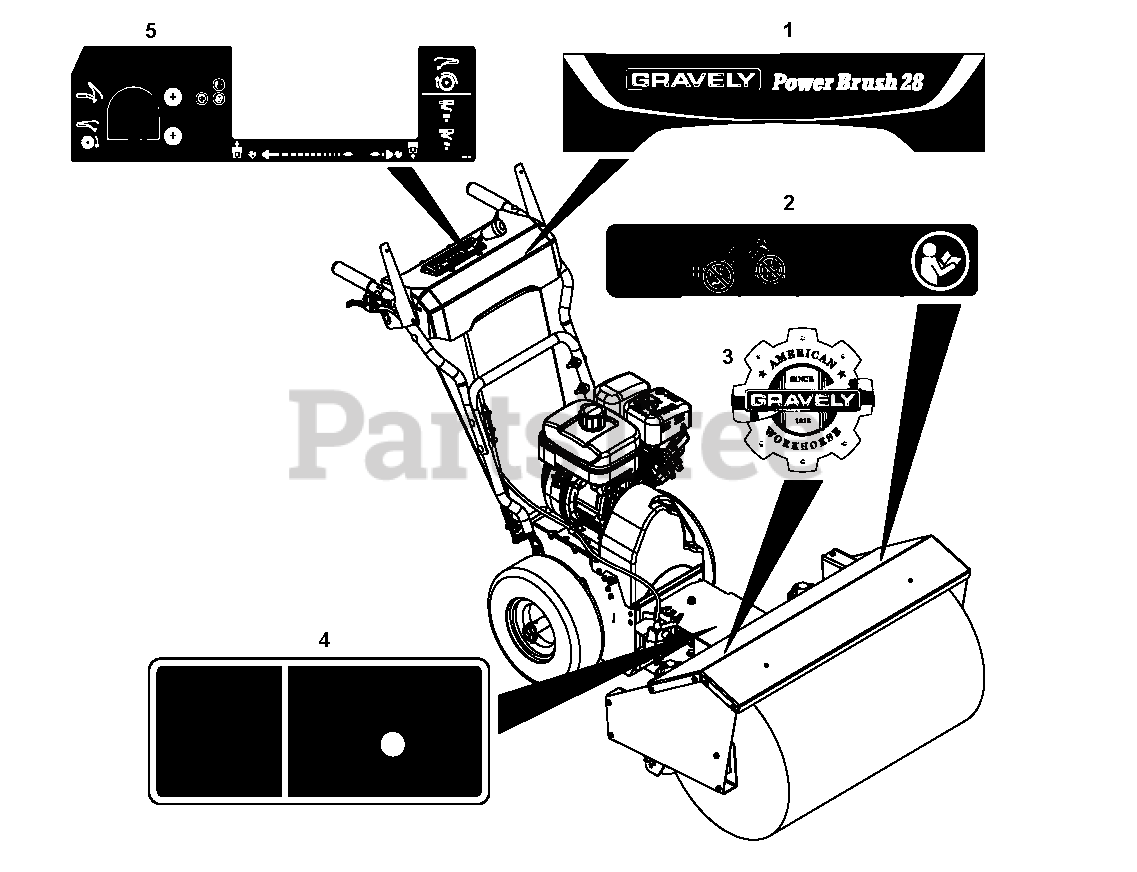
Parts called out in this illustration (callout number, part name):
1	Decal, Power Brush 28 - Gravely
2	Decal, Danger - Power Brush
3	Decal, Gravely Heritage
4	Decal, PTO Warning
5	Decal, Control
